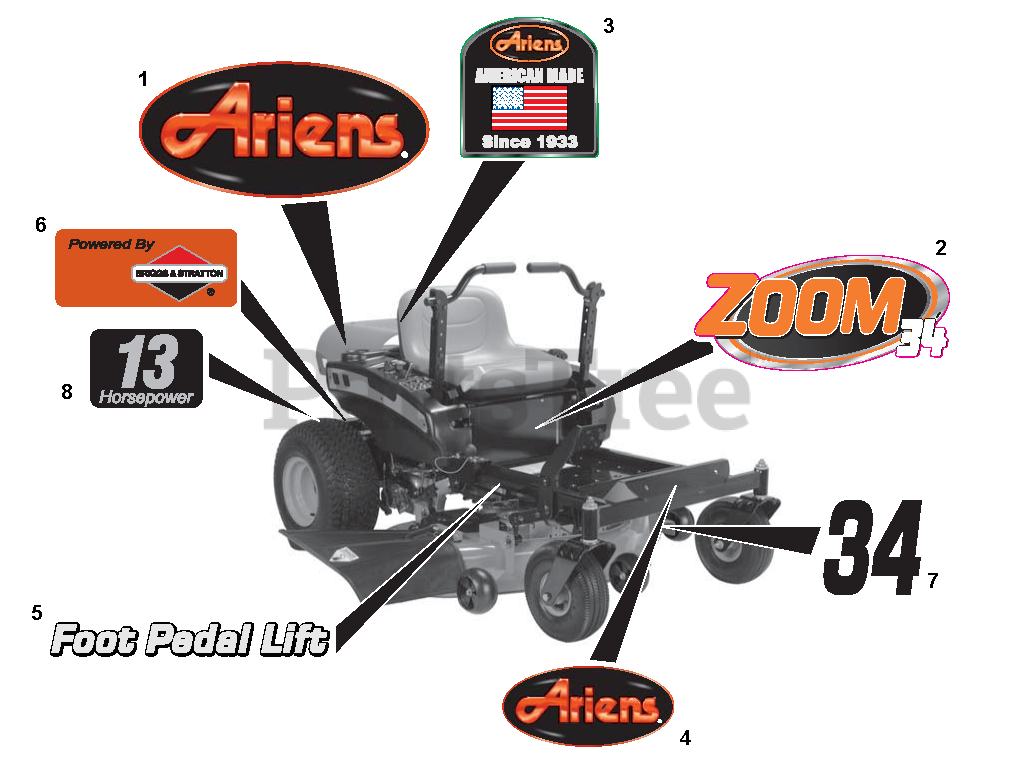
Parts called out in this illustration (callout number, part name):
1	DECAL, ARIENS JEWEL
2	DECAL, ZOOM 34
3	DECAL, MADE IN AMERICA(ARIENS)
4	DECAL. ARIENS DOMED JEWEL
5	DECAL, FOOT PEDAL LIFT
6	DECAL, POWERED BY B&S
7	DECAL, DECK SIZE, 34"
8	DECAL, 13 HP
